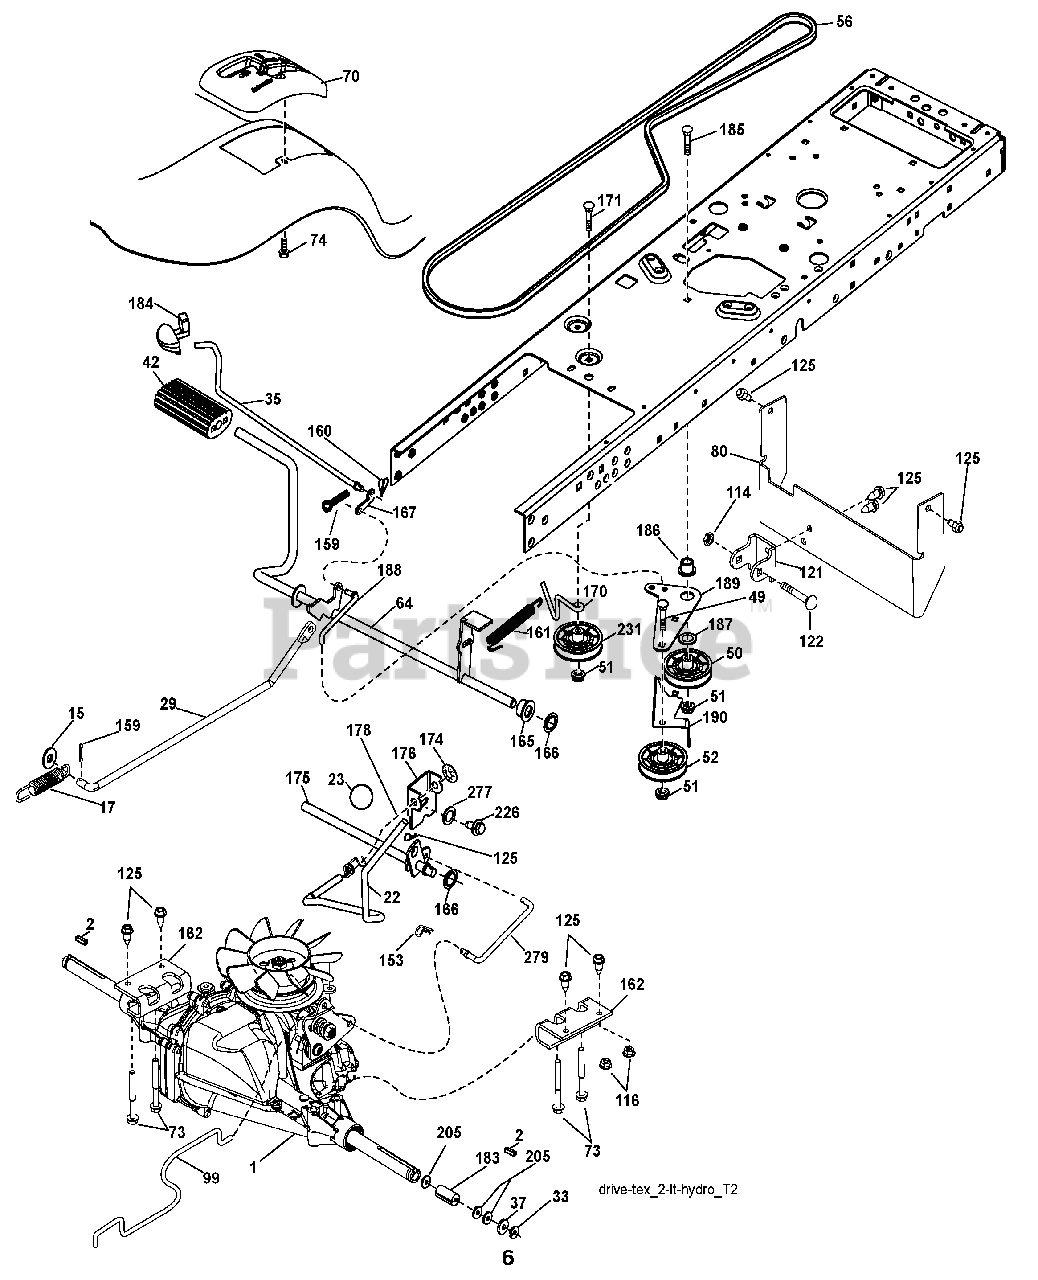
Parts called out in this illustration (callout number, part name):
1	Transaxle, Hydro Gear T2 (See Transaxle Breakdown)
2	Key Square
15	Washer 13/32 x 13/16 x 16 Ga.
17	Spring, Brake
22	Rod Shift
23	Knob
29	Rod, Brake
33	Ring E
35	Rod, Brake, Park
37	Washer 25/32 x 1-1/4 x 16 Ga.
42	Cover, Foot Pedal
49	Bolt
50	Pulley Idler Flat
51	Lock Nut 3/8-16
52	Idler V-Groove 910" Offset
56	V-Belt, Drive
64	Shaft Asm. Pedal Brake Control
70	Console
73	Bolt Hex 5/16-18 Gr. 5
74	Screw 1/4 x 1/2
80	Strap Torque
99	Rod Spring Bypass
114	Nut Lock 5/16-18 UNC
116	Nut Lock Hex Flange 5/16-18
121	Bracket Strap Torque
122	Bolt 5/16-18 x 2.50
125	Screw 5/16-18 x 3/4
153	Retainer Spring 1"
159	Pin Cotter 1/8 x 3/4
160	Retainer Clip
161	Spring, Return, Clutch
162	Adapter Transaxle
165	Bushing
166	Nut Push .625
167	Latch Brake Parking
170	Keeper Belt Centerspan
171	Bolt
174	Nut Push
175	Shaft Asm Shift
176	Arm Clevis Rod Shift
178	Spring Shift
183	Spacer Axle
184	Handle Parking Brake
185	Bolt
186	Spacer Retainer
187	Washer
188	Link Clutch Ground Drive
189	Bellcrank Ground Drive
190	Keeper Bellcrank Ground Drive
205	Washer 25/32 x 1-5/8 x 16 Ga.
226	Bolt 7/16-14 x 1 Gr 5
227	Washer Serrated
231	Idler V-Groove 1.688" Offset
279	Link Shift
